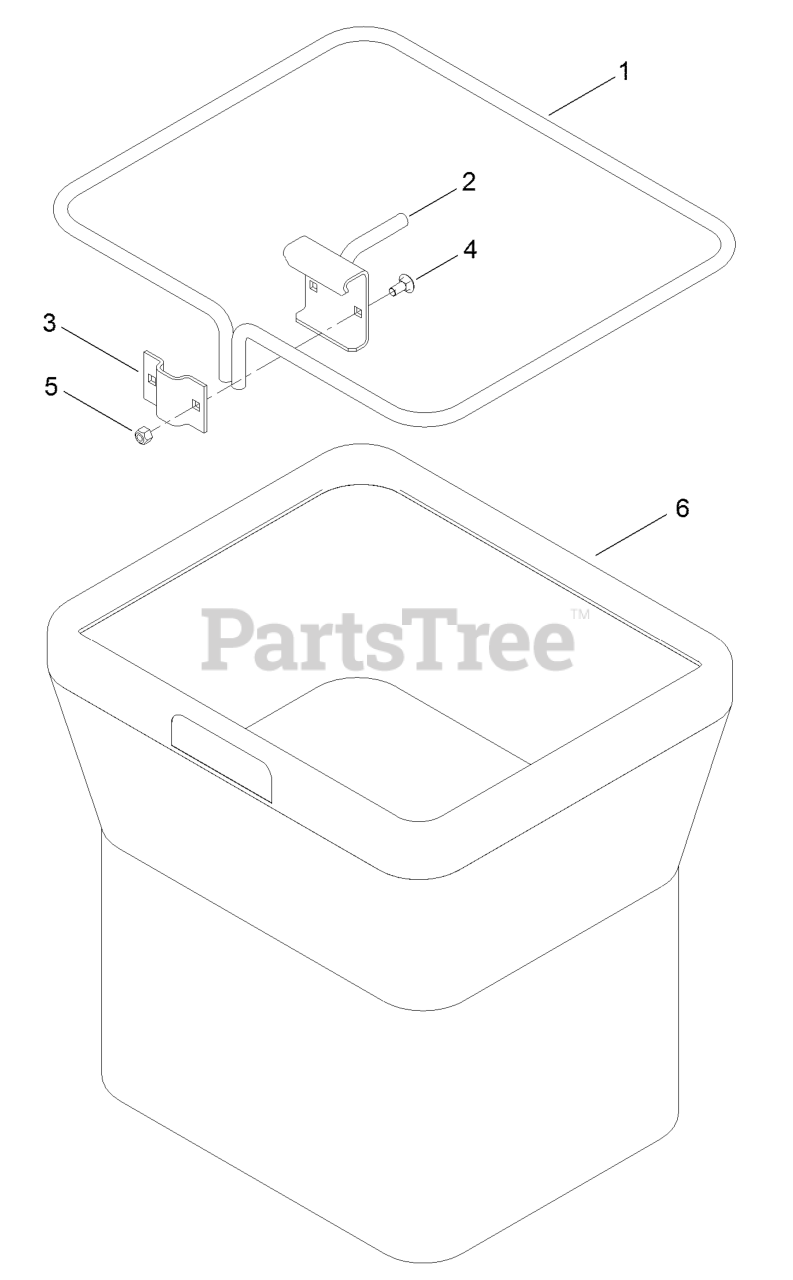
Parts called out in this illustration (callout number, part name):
1	FRAME-BAG
4	BOLT-CARR
5	NUT-LOCK, NI
